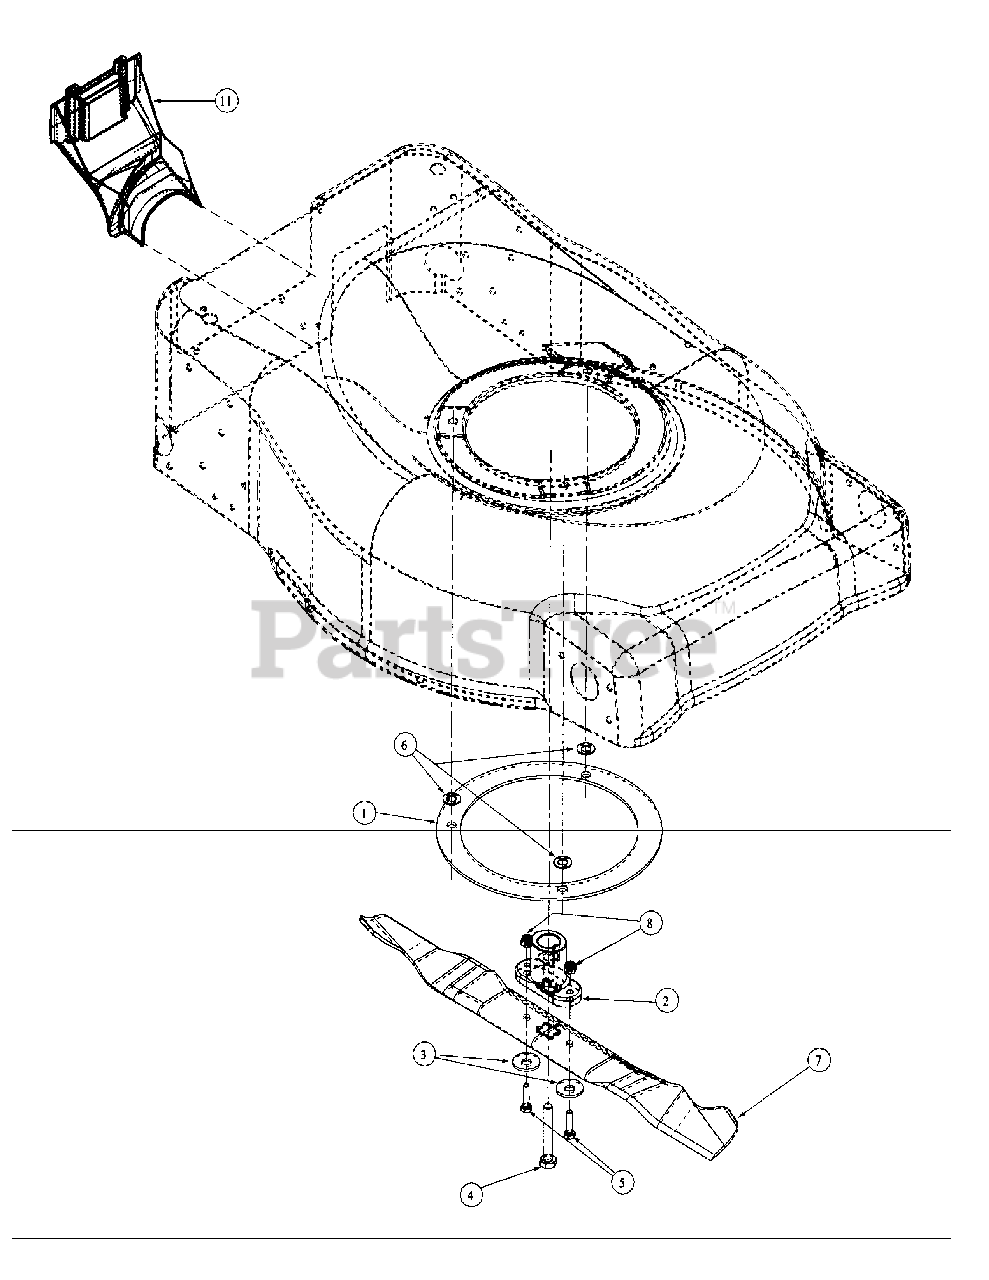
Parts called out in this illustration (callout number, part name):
1	Engine Mount Support Plate, W/0 BBC
2	Blade Adapter, 6 x 2.15 W/Star
3	Bell Washer, .396 x 1.140 x .095
4	HHCS: 3/8-24, 2.50, Group 8, Spec
5	HHCS, 1/4-20, 1.00, Group 5, Spec
6	Flat Washer, 3/8 X .738 X .063
7	Blade:21" Mulching W/Star
8	Hex Nut, 1/4-20, GRC, Lock
9	6.5 hp Briggs
11	Mulch Plug
